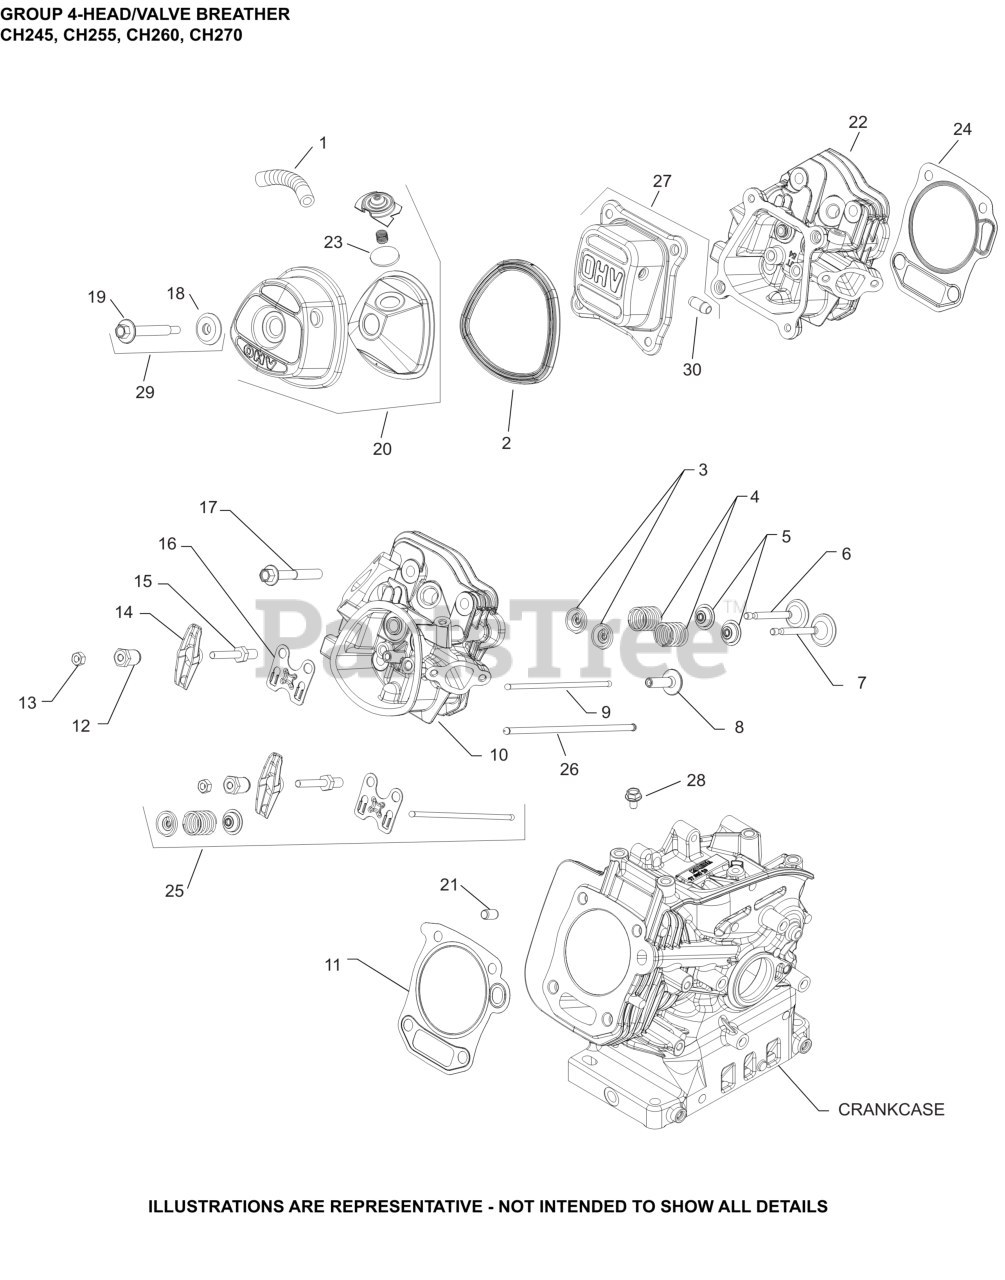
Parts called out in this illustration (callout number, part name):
1	TUBE, BREATHER - (#1812313S)
2	GASKET, VALVE COVER
3	RETAINER, VALVE SPRING
4	SPRING, VALVE
5	SEAL, VALVE STEM
6	VALVE, EXHAUST
7	VALVE, INTAKE
8	LIFTER, VALVE
9	ROD, PUSH-(#1741108S)
10	KIT, HEAD AND VALVE TRAIN
11	KIT, HEAD GASKET
12	PIVOT, ROCKER ARM
13	NUT, HEX JAM
14	ARM, ROCKER
15	STUD, ROCKER ARM-USE 14 072 22-S
16	PLATE, PUSHROD GUIDE
17	SCREW, HEX FLANGE CYL HEAD
19	SCREW, VALVE COVER SEAL ASSY
20	KIT, VALVE COVER
